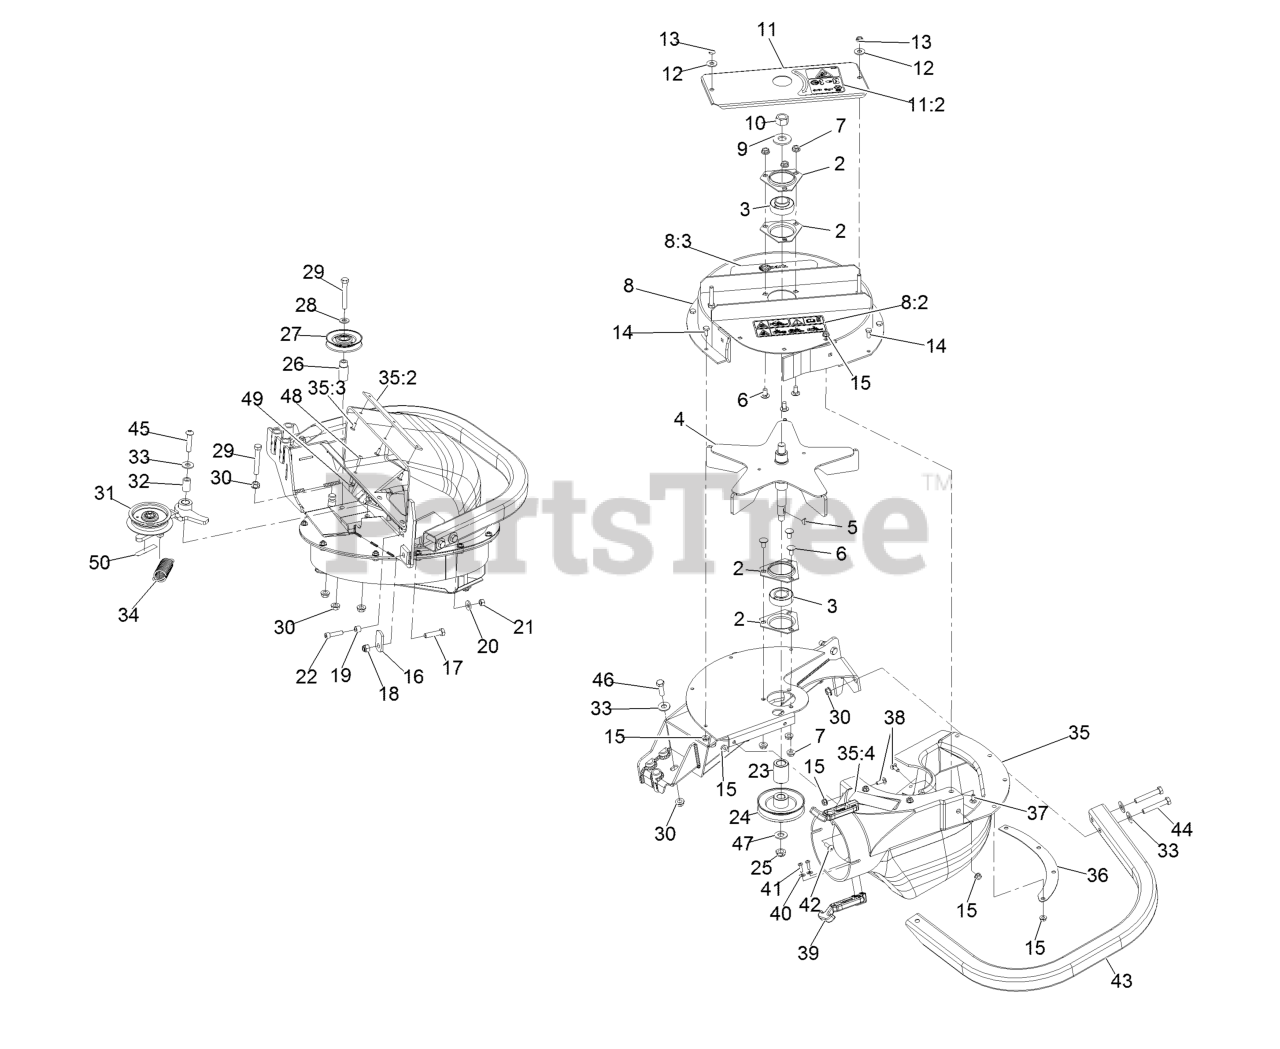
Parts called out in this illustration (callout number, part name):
2	HOUSING-FLANGE
3	BEARING
4	IMPELLER
5	KEY-WOODRUFF
6	SCREW-CARR
8	UPPER-HOUSING W/DECAL
8:2	Decal-Ultravac S-Series
8:3	DECAL-WARNING
9	WASHER-SPRING
10	NUT-HEX
11	COVER-BEARING W/DECAL
11:2	DECAL-WARNING
12	WASHER-FLAT
13	NUT-LOCK, NI
14	SCREW-HH
16	LATCH-CATCHER, GRASS
17	SCREW-HH
18	NUT-LOCK, NI
19	BUSHING, LOCATOR
20	WASHER-SPRING
21	NUT-HEX
22	SCREW-HSH
24	SHEAVE-BLOWER
25	NUT-LOCK, NI
27	IDLER-INSIDE
28	WASHER-FLAT
29	BOLT-CARR
30	NUT-HHF, WHIZ
31	ASM, IDLER
32	BUSHING-PIVOT, IDLER
33	WASHER-FLAT
34	SPRING-IDLER
35	ASM,BLOWER CHUTE LHP
35:2	PLATE-REINFORCEMENT
35:3	RIVET-BLIND
35:4	Decal-Warning
36	PLATE-BACKING, BLOWER
37	SCREW-CARR
38	BOLT-CARR
39	LATCH-RUBBER
40	WASHER-FLAT
41	SCREW-PPH
44	SCREW-HH
45	SCREW-HSBH
46	SCREW-HH
47	WASHER-FLAT
48	SCREW-HEAD, TRUSS
50	DECAL-WARNING
